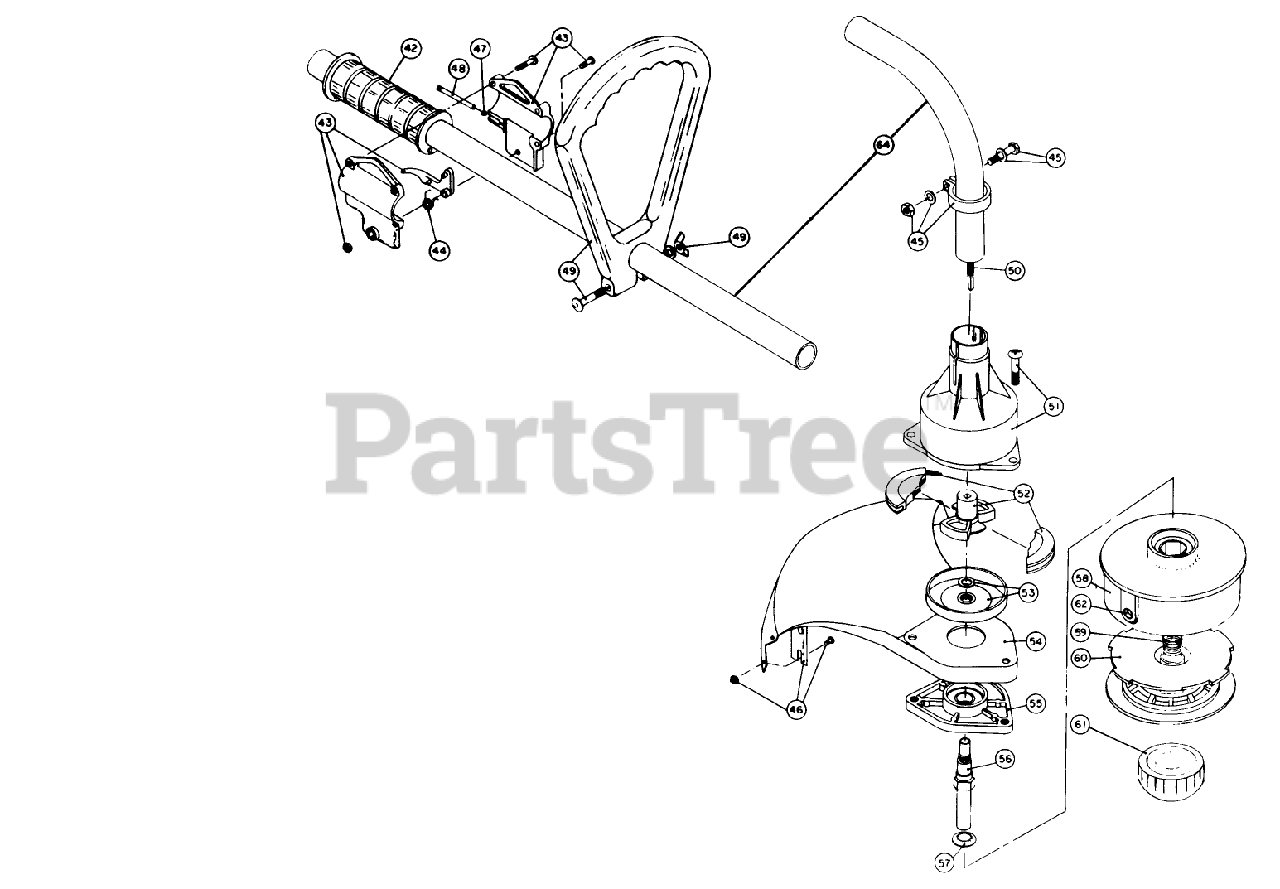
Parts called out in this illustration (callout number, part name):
44	THROTTLE TRIGGER SPRING
46	BLADE ASM
47	THROTTLE CABLE WIRE
48	THROTTLE CABLE HSG
51	CLUTCH HSG ASM
